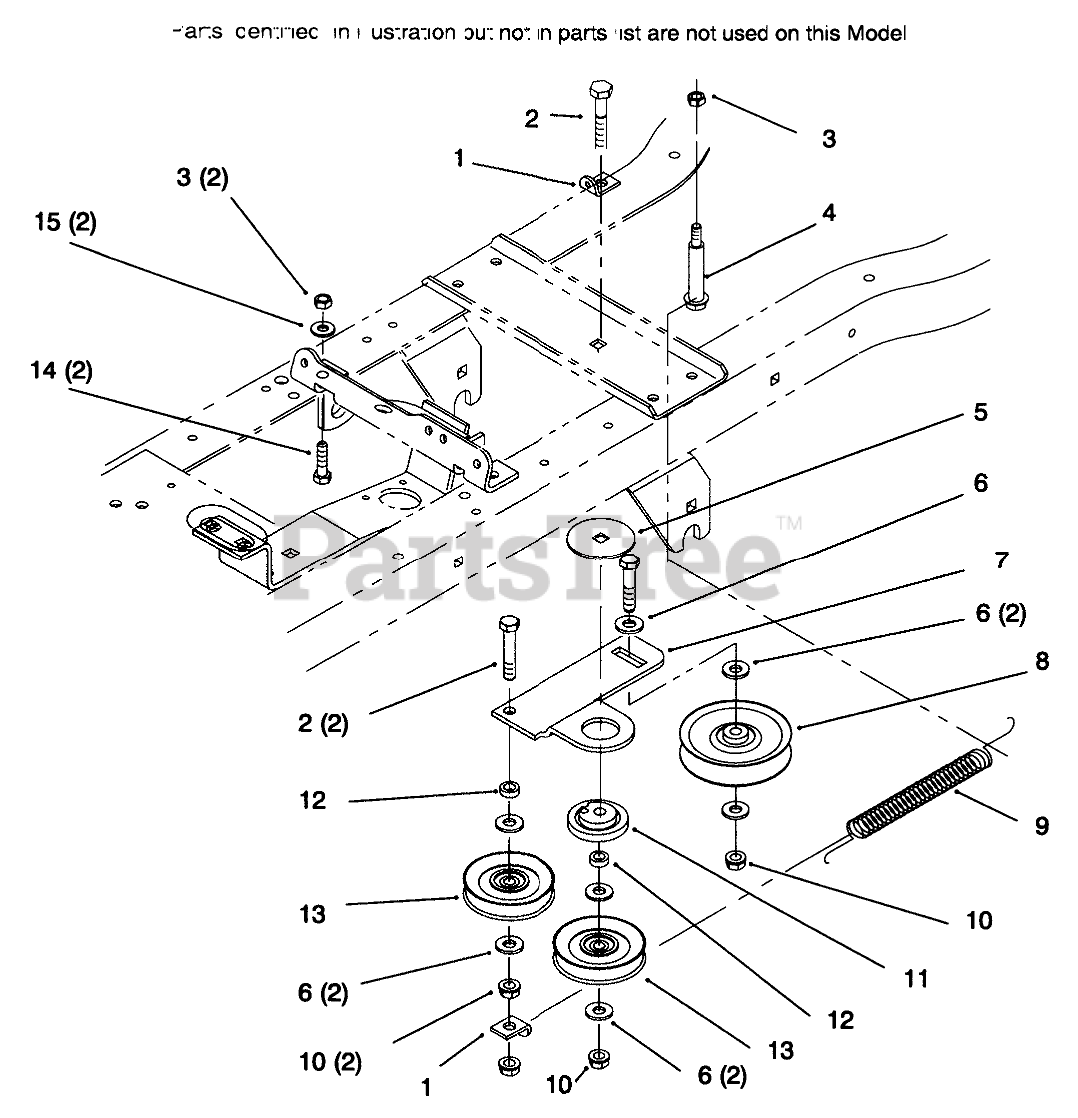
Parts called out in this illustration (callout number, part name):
1	CLIP - SPRING
2	SCREW-HH
3	NUT-LOCK, NI
4	BOLT-SHOULDER
5	WASHER-BEARING
6	WASHER-FLAT
7	ARM - IDLER
8	PULLEY-IDLER, FLAT
9	SPRING - CLUTCH
10	NUT-LOCK, NI
11	BUSHING
12	Spacer
13	PULLEY-IDLER
14	SCREW-HH
15	WASHER-PLAIN
